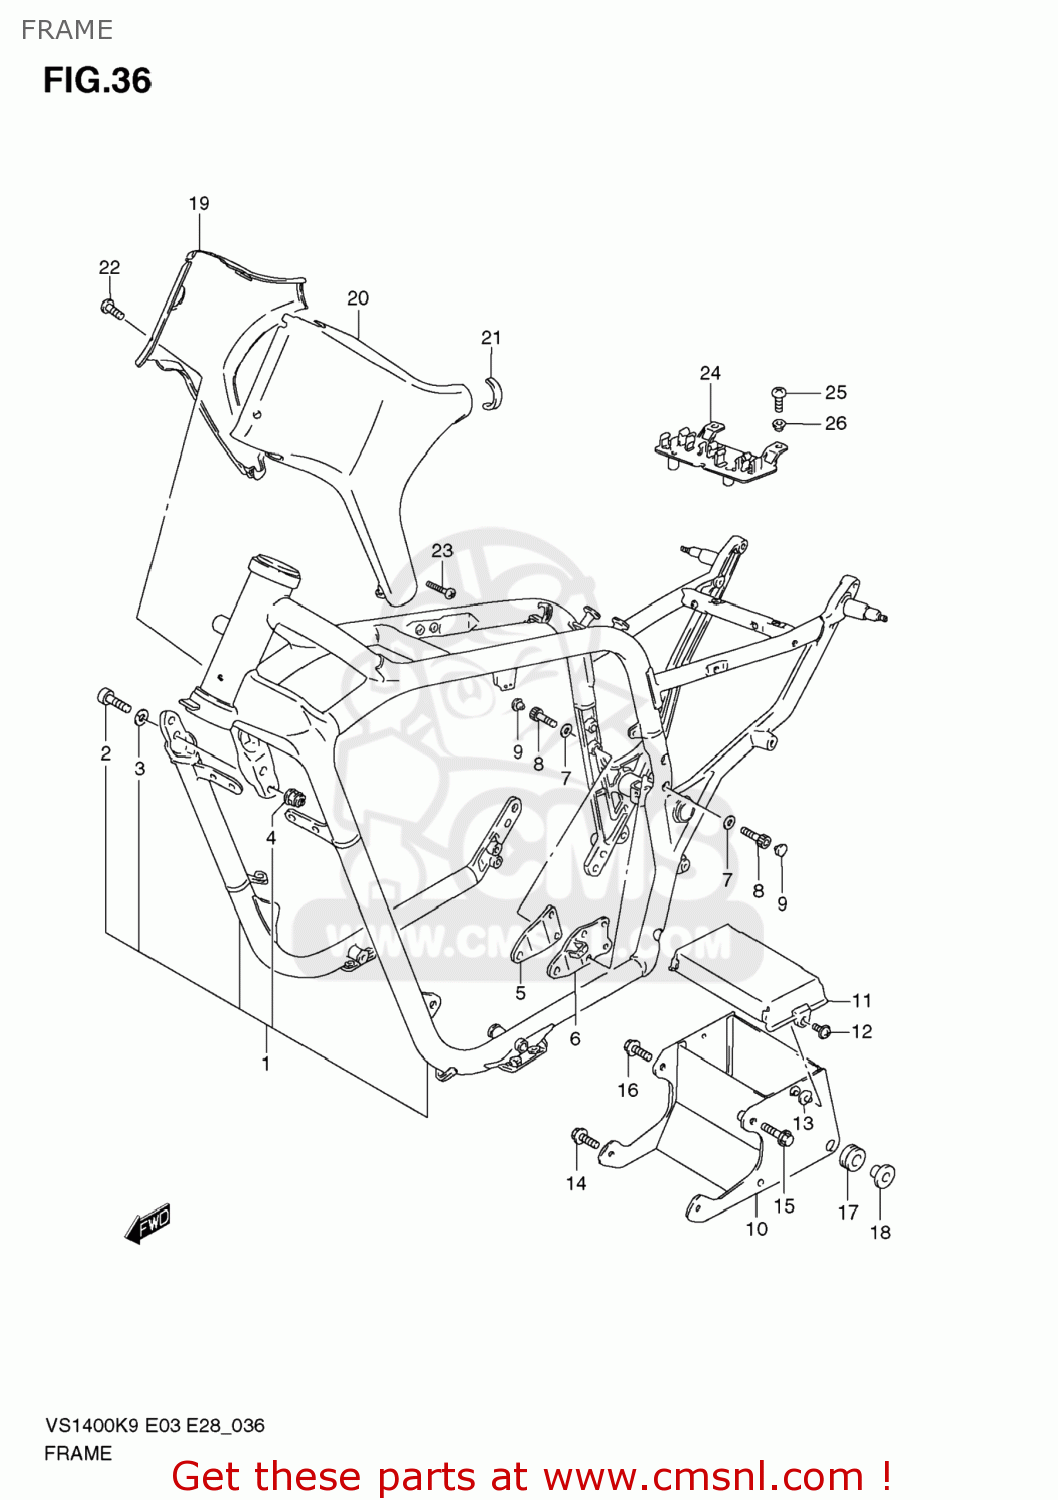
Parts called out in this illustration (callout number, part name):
1	FRAME SET(GRAY)
2	BOLT(10X33)
3	WASHER
4	NUT
5	PLATE,MOUNT NO.4,R
6	PLATE,MOUNT NO.4,L
7	WASHER
8	BOLT(8X32)
9	CAP(OD:14.5)
10	HOLDER,BATTERY
11	COVER,BATTERY
12	SCREW(5X12)
13	WASHER
14	BOLT
15	BOLT
16	BOLT(8X40)
17	CUSHION
18	BUSH
19	COVER,FRAME HEAD,R(GRAY)
20	COVER,FRAME HEAD,L(GRAY)
21	PROTECTOR,FRAME HEAD COVER
22	SCREW(6X10)
23	SCREW
24	HOLDER,COUPLER
25	SCREW
26	WASHER
